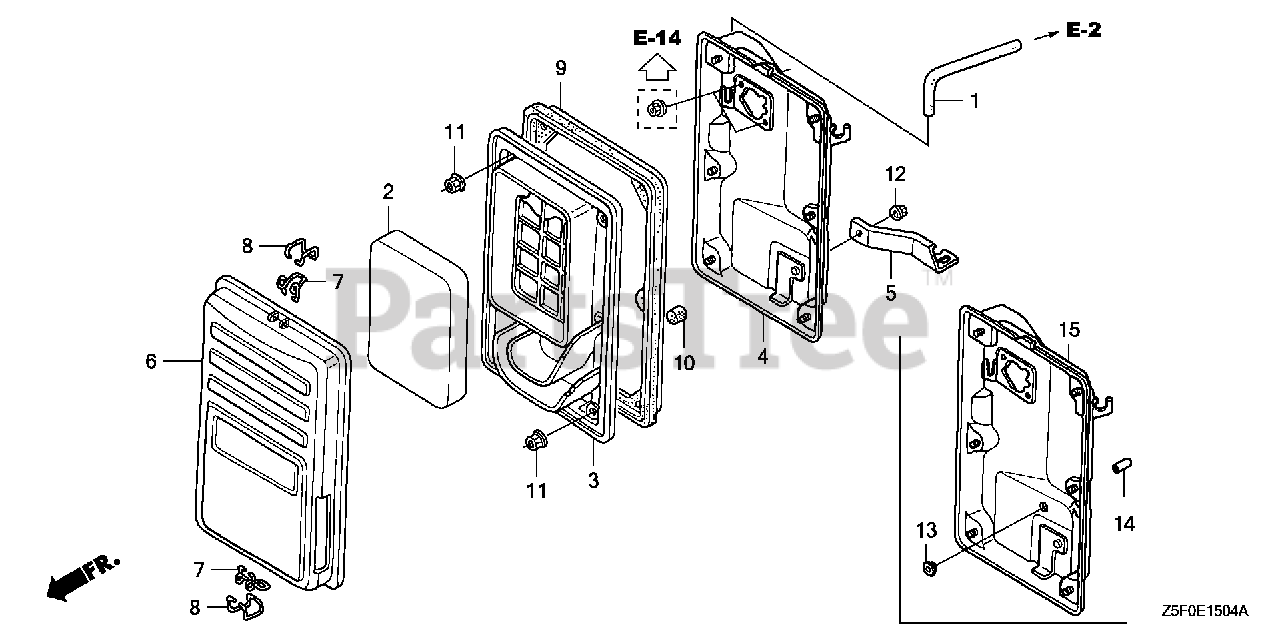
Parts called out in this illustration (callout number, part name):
1	TUBE, BREATHER
2	ELEMENT, AIR CLEANER
3	SEPARATOR, AIR CLEANER
4	HOUSING, AIR CLEANER
5	STAY, AIR CLEANER
6	COVER, AIR CLEANER
7	CLIP A, AIR CLEANER WIRE
8	CLIP B, AIR CLEANER WIRE
9	SEAL, AIR CLEANER
10	FILTER, DRAIN TUBE
11	NUT, FLANGE (5MM)
12	NUT, FLANGE (6MM)
13	GROMMET, AIR CLEANER
14	CAP, SEALING
15	HOUSING, AIR CLEANER
